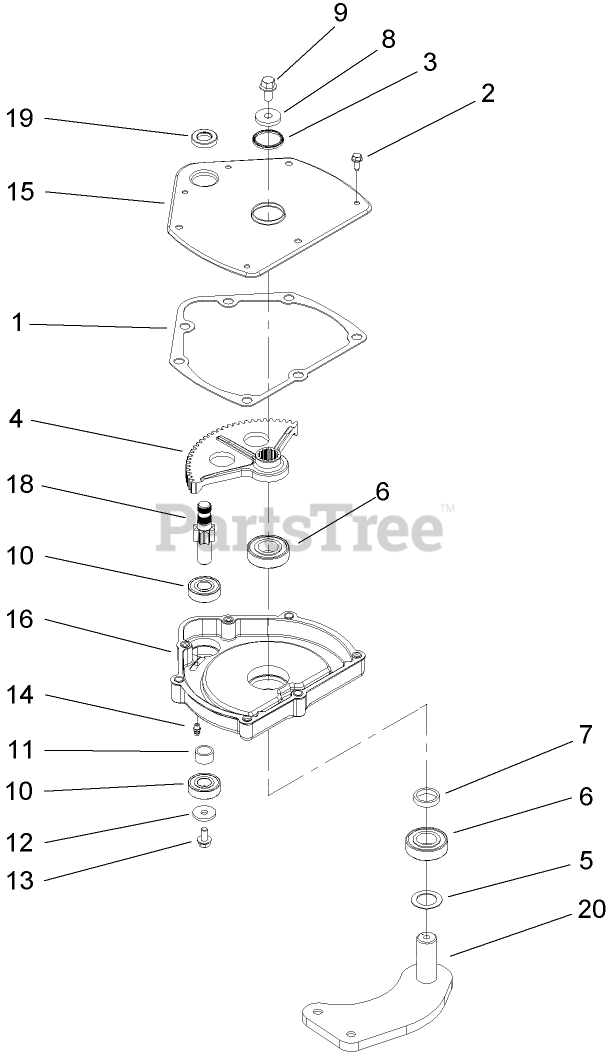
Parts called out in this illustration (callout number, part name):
1	GASKET
2	SCREW-HWH
4	SECTOR-GEAR
5	WASHER-FLAT
6	BEARING-BALL
7	SPACER-SHAFT, OUTPUT
8	WASHER-STEPPED
9	SCREW-HHF
10	BEARING-BALL
11	SPACER-SHAFT, INPUT
12	WASHER
13	SCREW-HH
14	FITTING-GREASE
16	HOUSING-STEERING
18	GEAR-PINION
19	SEAL-OIL
20	ARM-PITMAN
